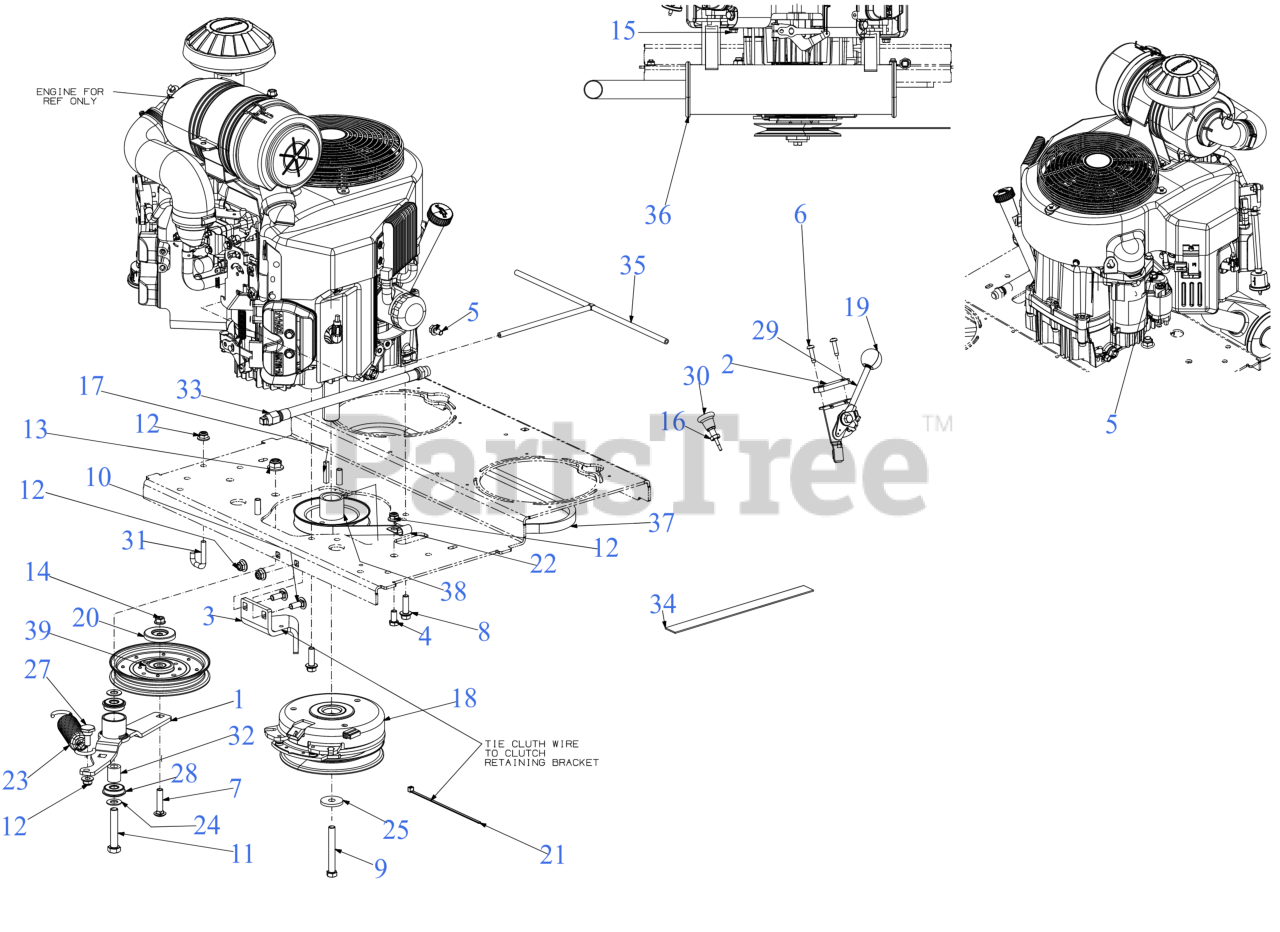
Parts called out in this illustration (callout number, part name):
1	TRANSMISSION IDLER BRACKET
3	CLUTCH RETAINER BRACKET
4	HEX SCREW 3/8-16 x .75
5	SCREW M8 x 1.25 x 16MM GR8.8
6	SCREW 1/4-20 x 1.0
7	CARRIAGE BOLT 3/8-16 x 1.75 GR5
8	SCREW 3/8-16 x 1.25 GR5
9	SCREW 7/16-20 x 3.25 GR5
10	CARRIAGE BOLT 3/8-16 x 1.00 GR5
11	SCREW 1/2-13 x 2.75 GR5
14	HEX LOCK NUT
15	HEX FLANGE NUT
16	HEX JAM NUT 3/8X24
17	SQUARE KEY 1/4 x 1.50
18	ELECTRIC PTO CLUTCH
20	PULLEY CAP
21	7" CABLE TIE
22	J TYPE CLIP
23	EXTENSION SPRING W/HOOK
24	FLAT WASHER .510 x .995
25	FLAT WASHER .45 x 1.5 x .172 HT
27	SHOULDER SCREW .625 x .302 x 3/8-16
28	ROLLER BEARING .5X1.37X.44
29	THROTTLE CABLE 59"
30	CHOKE CABLE
31	ROD SPRING HOOK
32	SPACER 0.51 x 0.88 x 1.00
33	OIL DRAIN HOSE
34	HEAT SHIELD 24"
35	ROLLOVER VENT HOSE ASSEMBLY
36	MUFFLER - KAWASAKI 1000
37	TRANSMISSION BELT
38	DRIVE PULLEY
39	IDLER PULLEY
